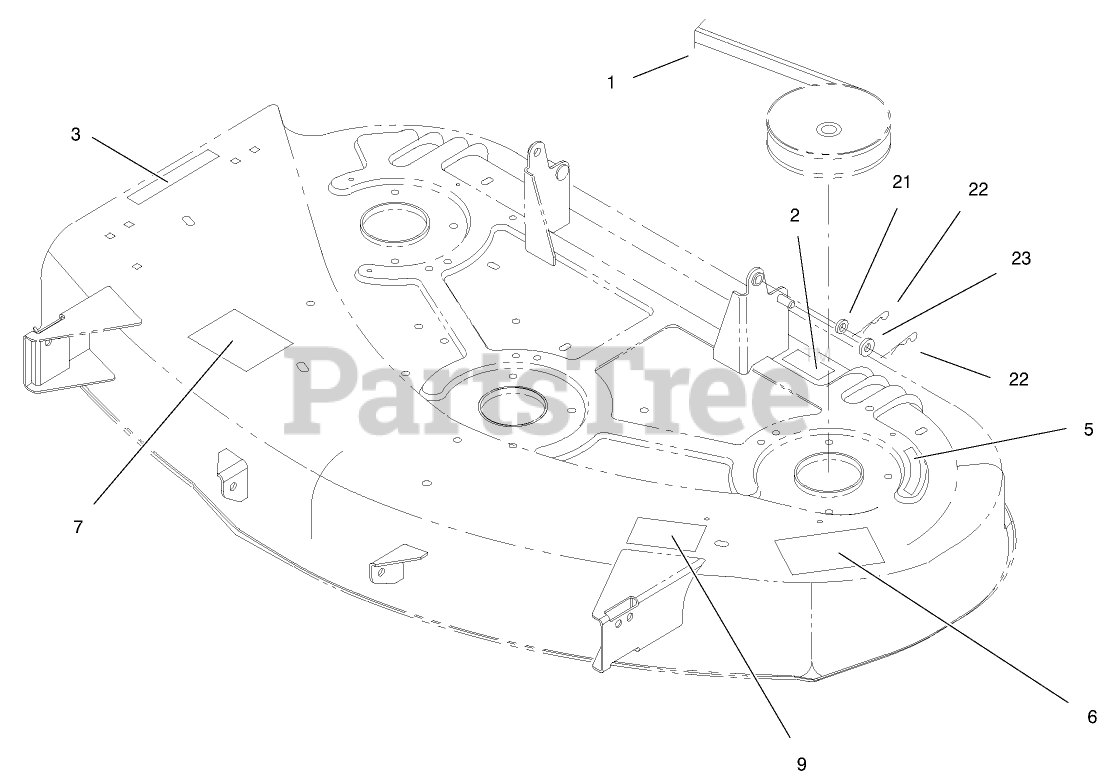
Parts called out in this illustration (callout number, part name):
1	BELT-V
2	DECAL-WARNING
3	DECAL-DANGER
5	DECAL-DANGER, SHIELD
6	DECAL-DANGER
7	DECAL-INSTALLATION, BELT
9	DECAL-ADJUSTMENT, WHEEL
21	WASHER-FLAT
23	WASHER-HARDENED
